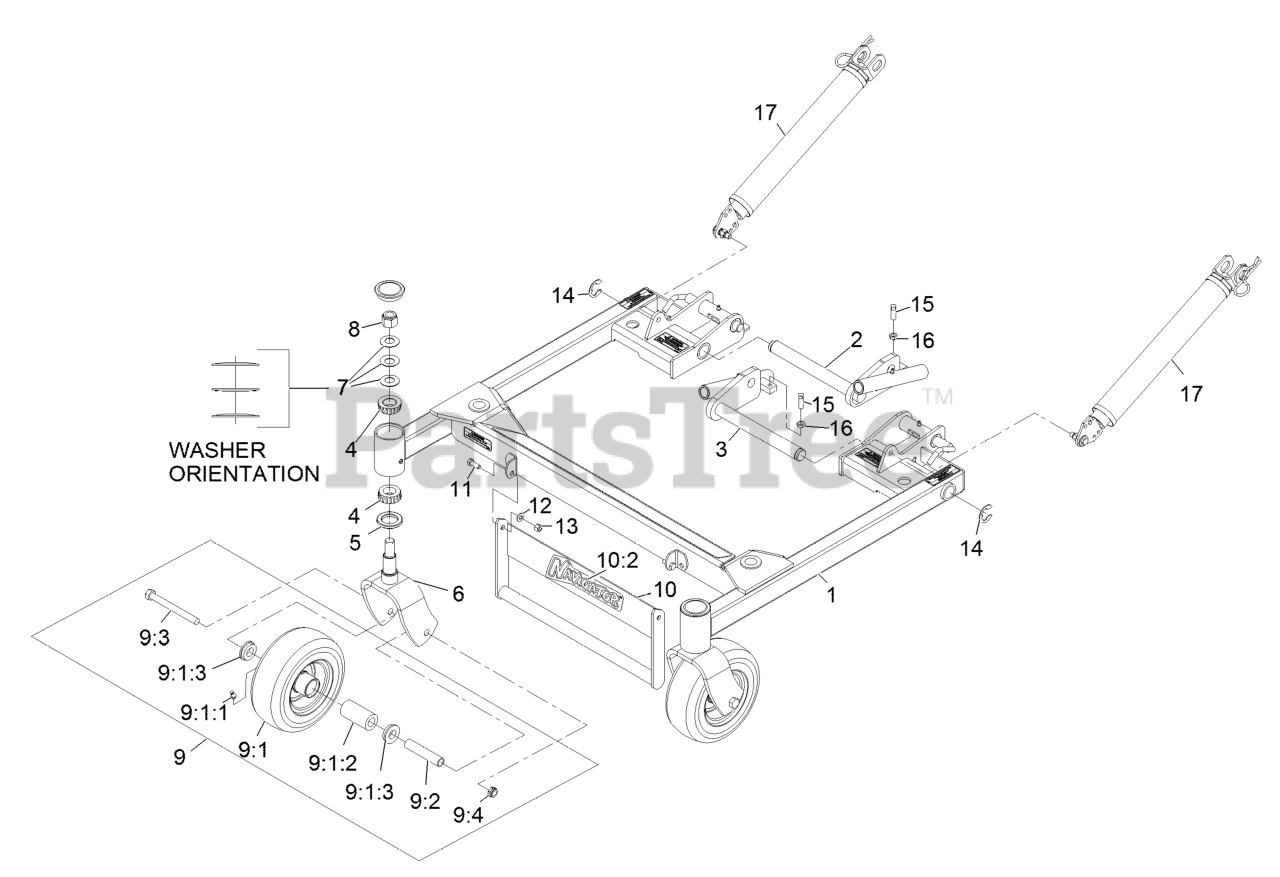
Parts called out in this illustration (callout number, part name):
1	DECK SUPPORT ASM
2	PIVOT-DECK, RH
3	PIVOT-DECK, LH
4	Cone-Bearing Tapered Roller
5	SEAL-GREASE
6	FORK-CASTER
7	WASHER-BELLVILLE
8	NUT-LOCK, NI
9	ASM,FF CASTER WHEEL W/AXL
9:1	ASM,WHEEL,TIRE & BRGS 8X3
9:1:1	FITTING-GREASE
9:1:2	BEARING-ROLLER, STRAIGHT
9:1:3	BUSHING
9:2	SPACER-CASTER, FRONT
9:3	SCREW-HH
9:4	NUT-HEX
10	ASM,DECK LIFT HANDLE W/DE
10:2	DECAL,NAVIGATOR MODEL
11	SCREW-HH
12	WASHER-SPRING
13	NUT-LOCK, NI
14	RING-SNAP
15	SCREW-SET, SQH
16	NUT-JAM
17	LIFT ASSIST SPRING ASM
